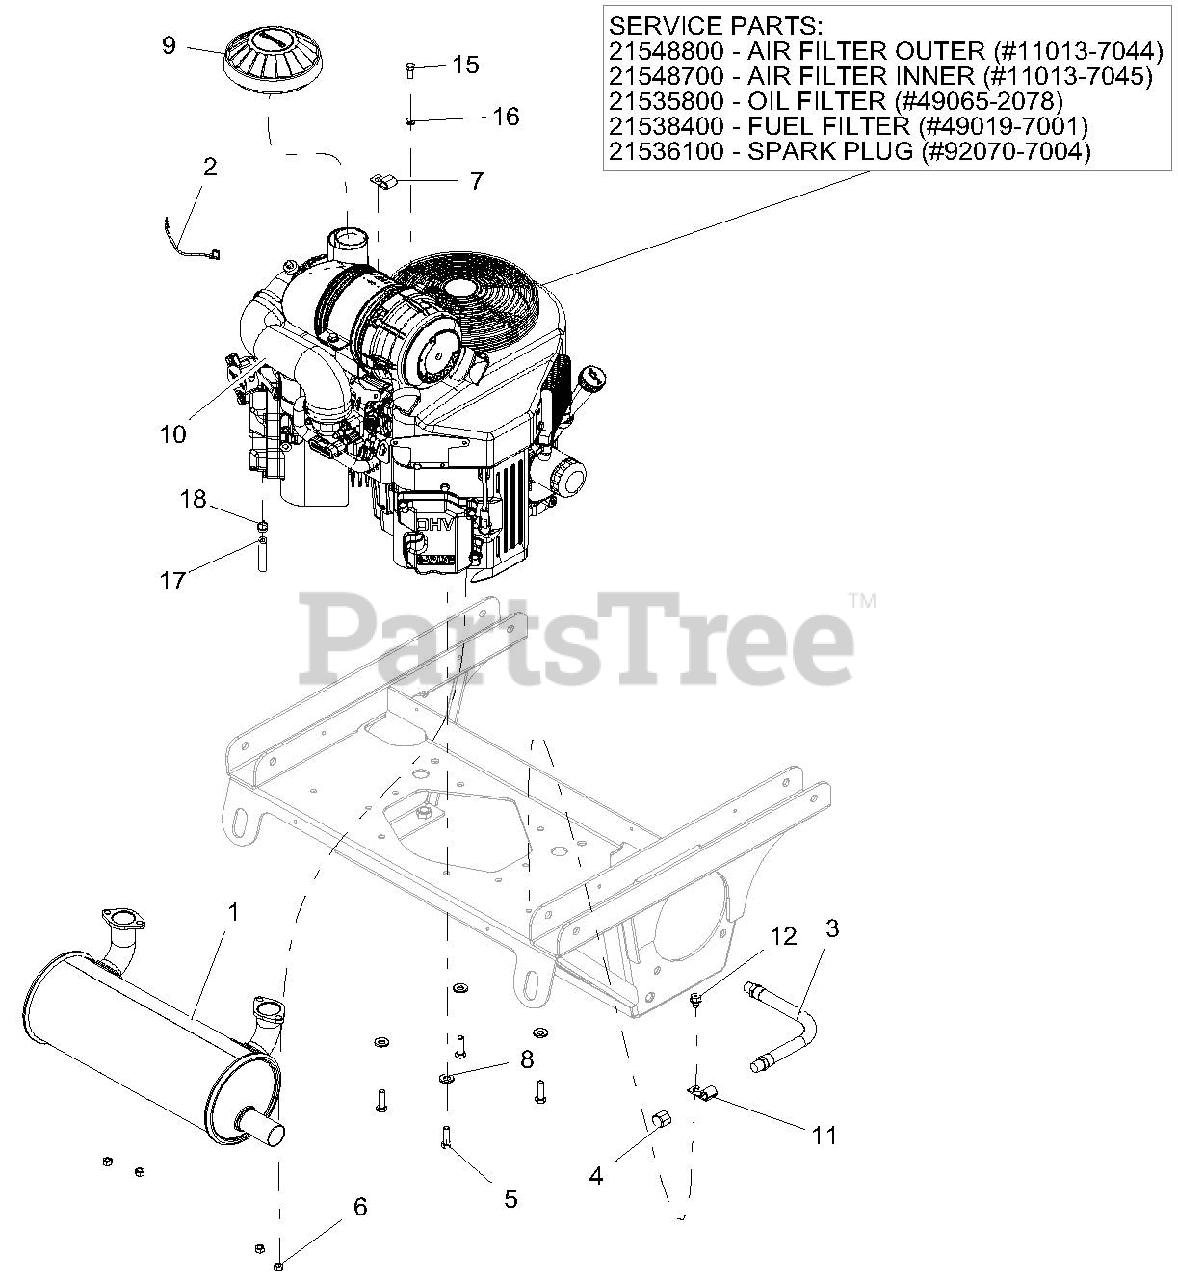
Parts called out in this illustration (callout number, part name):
1	MUFFLER - 34HP KAWASAKI VERT
2	LEAD - STARTER SOLENOID
3	HOSE, HYD .38-11-0K M6N0-M6N0
4	PIPE, CAP 3/8 NPT FEMALE
5	BLT-HEX .38-16X1.25 GR5 YWZC NYTORQ
6	NUT-LK-TOP M8-1.25 YWZC
7	CLAMP, J
8	WSHR, 3/8" SPRING DISC
9	CAP, AIR CLEANER INTAKE
10	ENGINE, KAWASAKI FX921
10	AIR FILTER OUTER (#11013-7044)
10	AIR FILTER INNER (#11013-7045)
10	OIL FILTER (#49065-2078)
10	FUEL FILTER (#49019-7001)
10	SPARK PLUG (#92070-7004)
12	SCR-TAP .38-16X.50 HWH TR YWZ
15	@ BLT-HEX M8-1.25X20 YWZC
16	WSHR-LK .31X.078 REG YWZC
17	.25 LOW-PERM GAS HOSE 28.00" LG
18	CLAMP, FUEL LINE
